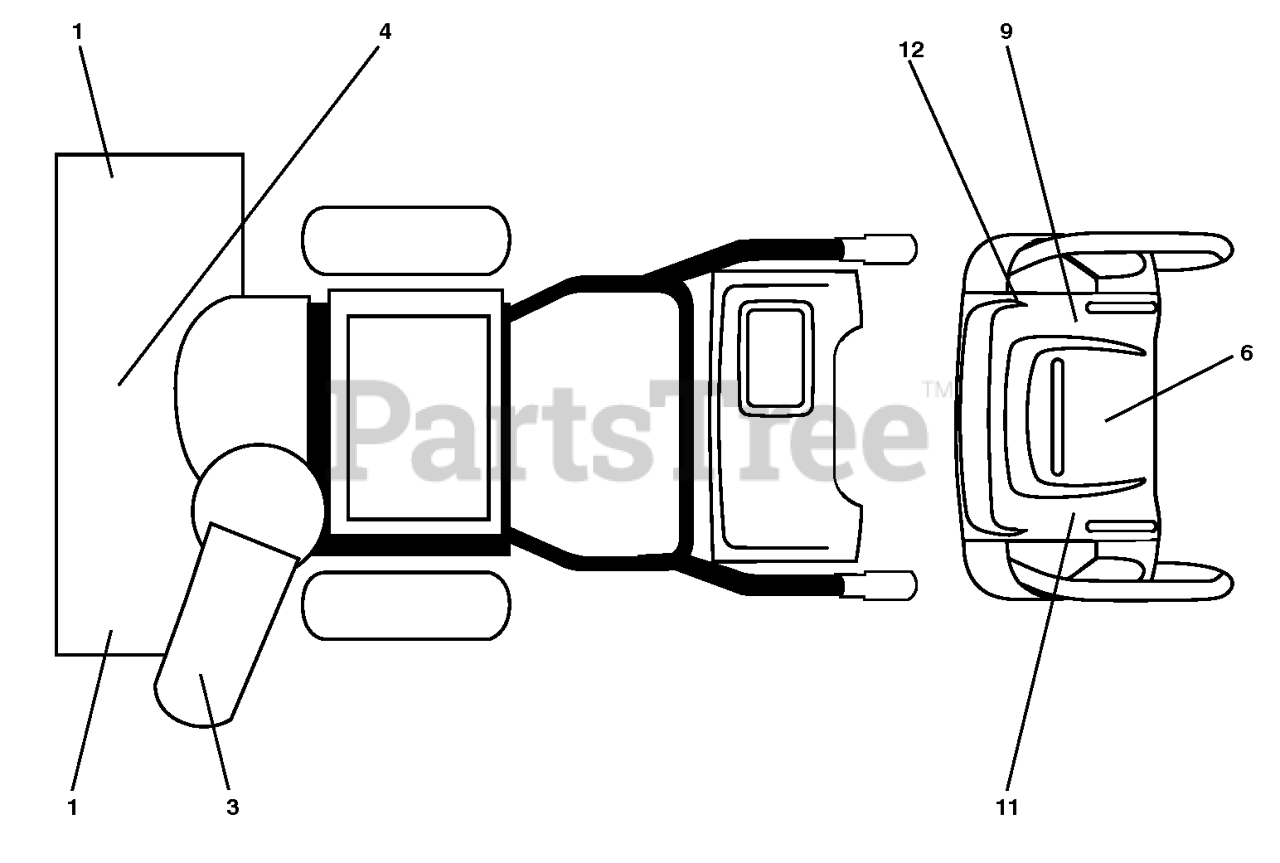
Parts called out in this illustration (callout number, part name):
1	DECAL.SNOWTHR.AUGER
3	DECAL.SNOWTHR.CHUTE.SAFETY
4	DECAL.SNOWTR.READ.OWN.MAN.E/F
6	DECAL.CONSOLE.SNOW.INST.ENG/FR
9	DECAL.CONS.RT.SPD/LEV/PWRST.
11	DECAL.CONS.LT.SPD/LEV/PWRST.
12	DECAL.CONSOLE.HAND.WARMER
